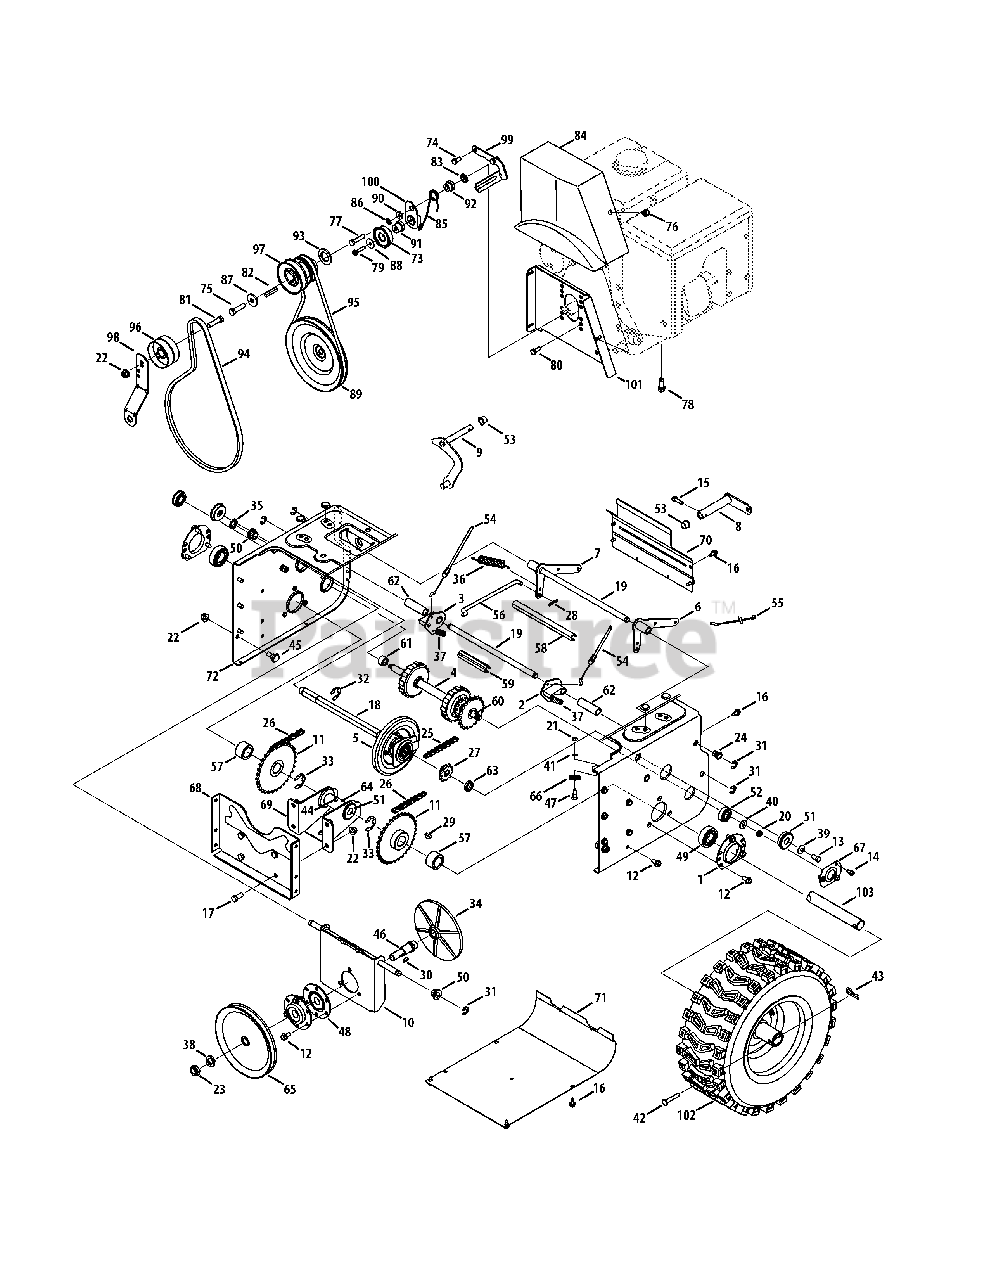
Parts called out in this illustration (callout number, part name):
1	Housing, Bearing
2	Dogg, Steering Drive, LH
3	Dogg, Steering Drive, RH
4	Shaft Assembly, Steering
5	Assembly, Friction Wheel
5	Wheel, Friction, Bonded
5	Screw, Hex Wash
6	Bracket, Auger Actuator
7	Bracket, Drive Actuator
9	Rod Assembly, Shift
10	Brkt, Friction Drive Suprt.
11	Sprocket, 32T
12	TT Screw, 5/16-18 x .750
13	Screw, Hex Cap Lock,
14	Screw, Hex, 1/4-20 x .50
15	Screw, Hex, 1/4-20 x 1.00
16	Screw, Hex Wash.
17	Screw, Hex Cap, 3/8-16
18	Shaft, Hex Drive
19	Shaft, Actuator
20	Nut, Hex Insert Jam Lock
21	Nut, Hex, 1/4-28 GR5
22	Nut, Hx Flnge Insert Lk
23	Nut, Hx Insert Jam Lk
24	Nut, Insert 3/8-16
25	Chain, Endless, #41 x 36L
26	Chain, #420 x 40L
27	Sprocket, #41 x 10T
28	Pin, Internal Cotter
29	Key, Woodruff
30	Key, Hi-Pro, 3/16 x 5/8
32	Ring, Retaining
33	Ring, Retainer
34	Plate, Drive
35	Speed Nut, .500
36	Spring, Extension
37	Spring, Extension
38	Washer, Lock, 5/8
39	Washer, Bell., .34 x .872 x .06
40	Washer, .406 x .875 x .059
41	Washer, Lock, 1/4
42	Pin, Clevis
43	Pin, Internal Cotter
44	Fitting, Lube, 3/16 Drive
45	Screw, Shldr., .498 x .34
46	Spindle, Drive Plate
47	Screw, Hex Shldr., 1/4-28
48	Ass’y, Bearing/Housing
49	Bearing, Self Aligning
50	Bearing, Hex Flange
51	Bearing, Ball
52	Bush, Flg, .5625 ID x 1.375 x .4375
53	Bush, Flg, .5 ID x .627 OD
54	Cable, Steering
55	Cable, Auger Idler
56	Rod, Drive Clutch
57	Spacer, 1.01 x 1.50 x .93
58	Spacer, .49 x 7.865
59	Spacer, .49 x 3.545
60	Spacer, .566 x .87 x .190
61	Spacer, .566 x .87 x 1.25
62	Spacer, .514 x .632 x 2.44
63	Spacer, .675 x 1.0 x .23
64	Spacer .6725 x 1.125 x 2.48
65	Pulley, Drive
66	Roller, Cable
67	Retainer Bracket
68	Bracket, Frame Support
69	Bracket, Axle Support
70	Cover, Upper Frame
71	Cover, Lower Frame
72	Trans Frame
73	Idler Pulley Assembly
74	Screw, Hex 5/16-24 x .75
75	Screw, Hex 3/8-24 x 1.25
76	Screw, Hx Wash Hd Tapp
77	Screw, Hex Cap, 5/16-24 x 1.50
78	Screw, 3/8-16 x 1.00
79	Screw, 1/4-20 x 1.25
80	Screw, Shldr., .500 x .145
81	Screw, Hex Cap, 3/8-16 x 1.75
82	Key, Square, 1/4 x 1.5
83	Nut, Push
84	Cover, Belt
85	Torsion Spring, .850 dia. x .333 lg.
86	Washer, Lock, 5/16
87	Washer, Flat, .406 x 1.25
88	Washer, Flat, .265 x 1.0 x .030
89	Auger Pulley, 10.0 x .5
90	Shldr. Spacer, .3175 x .500 x .094
91	Shldr. Spacer, .260 x .785 x .538
92	Shoulder Spacer, .340 x 1.00
93	Spacer, 1.02 x 1.63 x .1425
94	V-Belt, 4L x 44.60
95	V Belt, 3/8 x 36.68
96	Pulley, Flat Idler, 2.75 OD
97	Double Pulley, 3.25 x 2.75
98	Bracket, Auger Idler
99	Belt Keeper Bracket
100	Idler Drive Wheel Bracket
101	Belt Cover Bracket
102	Wheel Ass’y. - LH
103	Axle, Wheel, 45"
